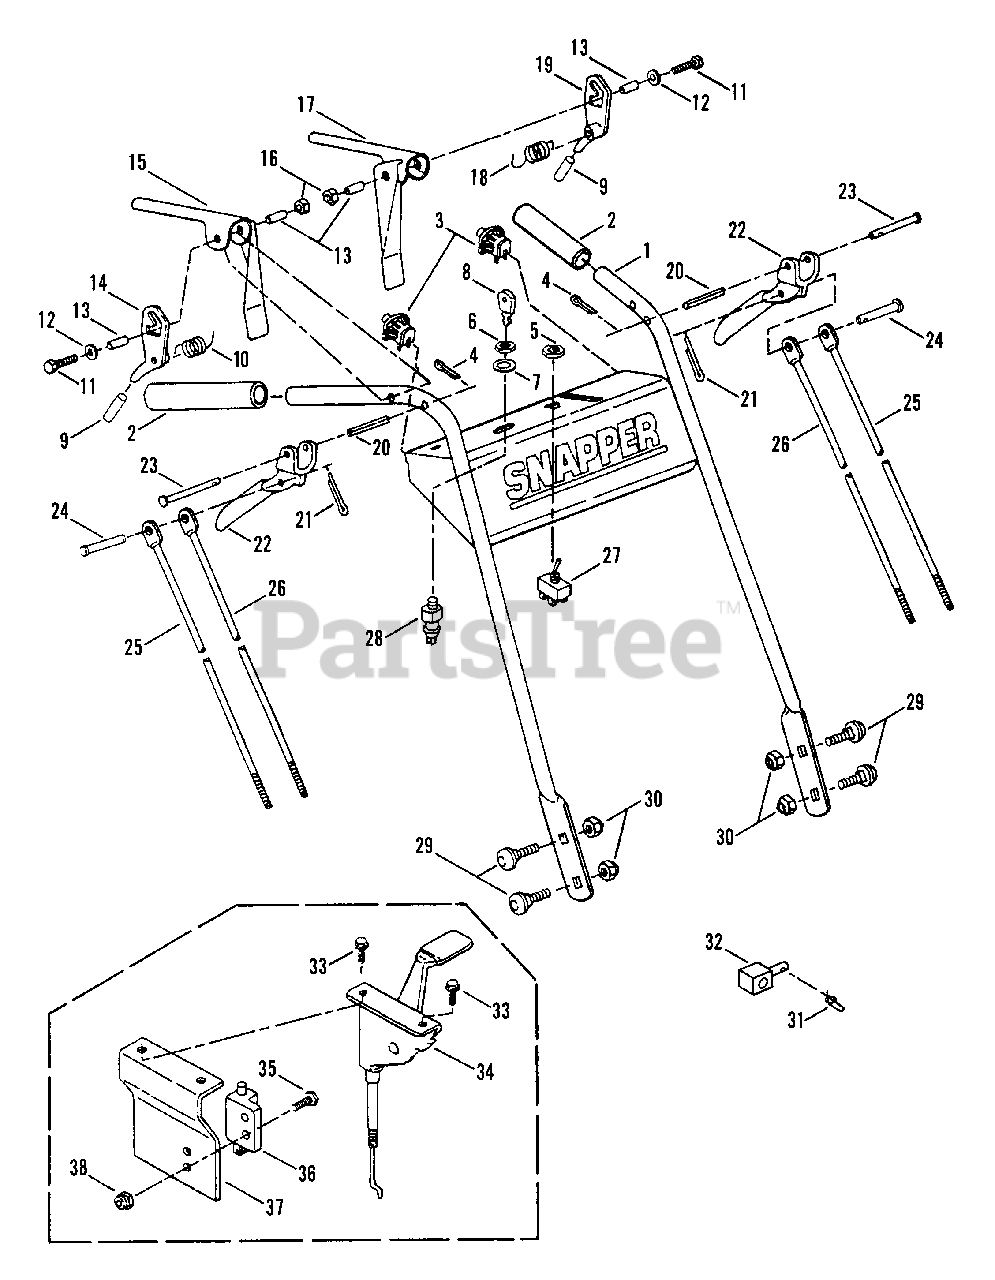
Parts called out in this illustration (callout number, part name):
1	ASSEMBLY, Handle, Pistol Grip
2	GRIP, Handle Assembly
3	SWITCH, OPC
4	PIN, .06 x .50" Cotter
5	NUT, 1/2-27 Hex (Special)
6	NUT, 5/8-32 Hex (Special)
7	WASHER, 5/8 Internal Tooth Lock
8	KEY, Switch (With Cover)
9	GRIP, Latch
10	SPRING, Torsion (Left Hand)
11	BOLT, 1/4-20 X 2-1/2", GD5
12	WASHER, 1/4 Flat
13	SPACER, OPC
14	LATCH (Right Hand)
15	GRIP, Pistol, OPC (Right Hand)
16	NUT, 1/4-20 Hex Lock
17	GRIP, Pistol, OPC (Left Hand)
18	SPRING, Torsion (Right Hand)
19	LATCH (Left Hand)
20	PIN, 5/16 x 1-1/8" Roll
21	PIN, 3/32 x 1" Cotter
22	LEVER, Drive (With Grip)
23	PIN, 3/16 x 1 3/4" Clevis
24	PIN, 5/16 x 2" Clevis
25	ROD, Traction
26	ROD, Traction Brake
27	SWITCH
28	SWITCH, ON-OFF
29	BOLT, 3/8-16 x 1" Short Neck Carriage, Grade 2
30	NUT, 3/8-16 HEX NYLON LOCK
31	COTTER-PIN, 1/2" Self-Locking
32	SWIVEL
33	SCREW, #10-24 x 1/2" Hex Washer Self-Tap (Torx)
34	CONTROL, Throttle (Kohler Engines)
35	SCREW, #10-24 x 1/2" Hex Head, Machine
36	SWITCH, OPC
37	BRACKET, Reverse Throttle
38	NUT, #10-24 Hex Nyloc
